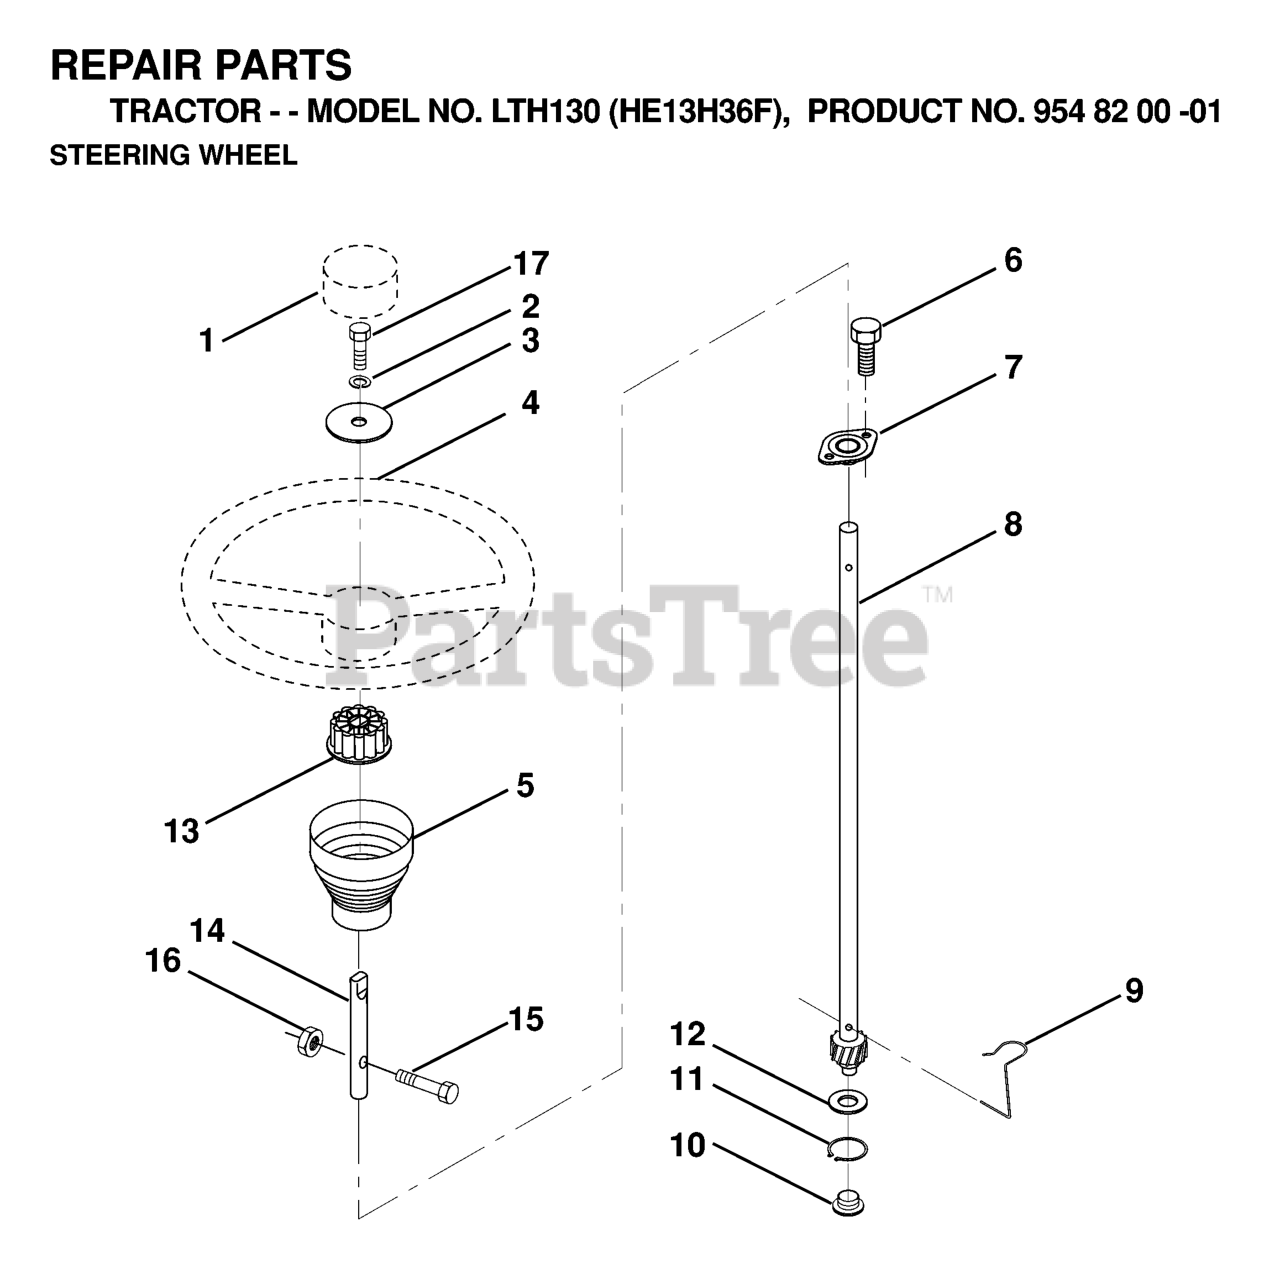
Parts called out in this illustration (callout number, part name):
1	INSERT,STR WHEEL
2	WASHER, LOCK 3/8
3	WASHER T
4	STEERING WHEEL
5	STEERING SLEEVE
6	SCREW.TT.#10-32X.5.3/8.FLANGE
7	BUSHING
8	STEERING SHAFT
9	STEERING CLIP
10	BUSHING STEER LWR
13	ADAPTER LT
14	EXT SHAFT STEERING
15	BOLT.5/16-18X1-1/4 FULL.THREAD
16	NUT.71038.31-18.HEX.NYLOCK
